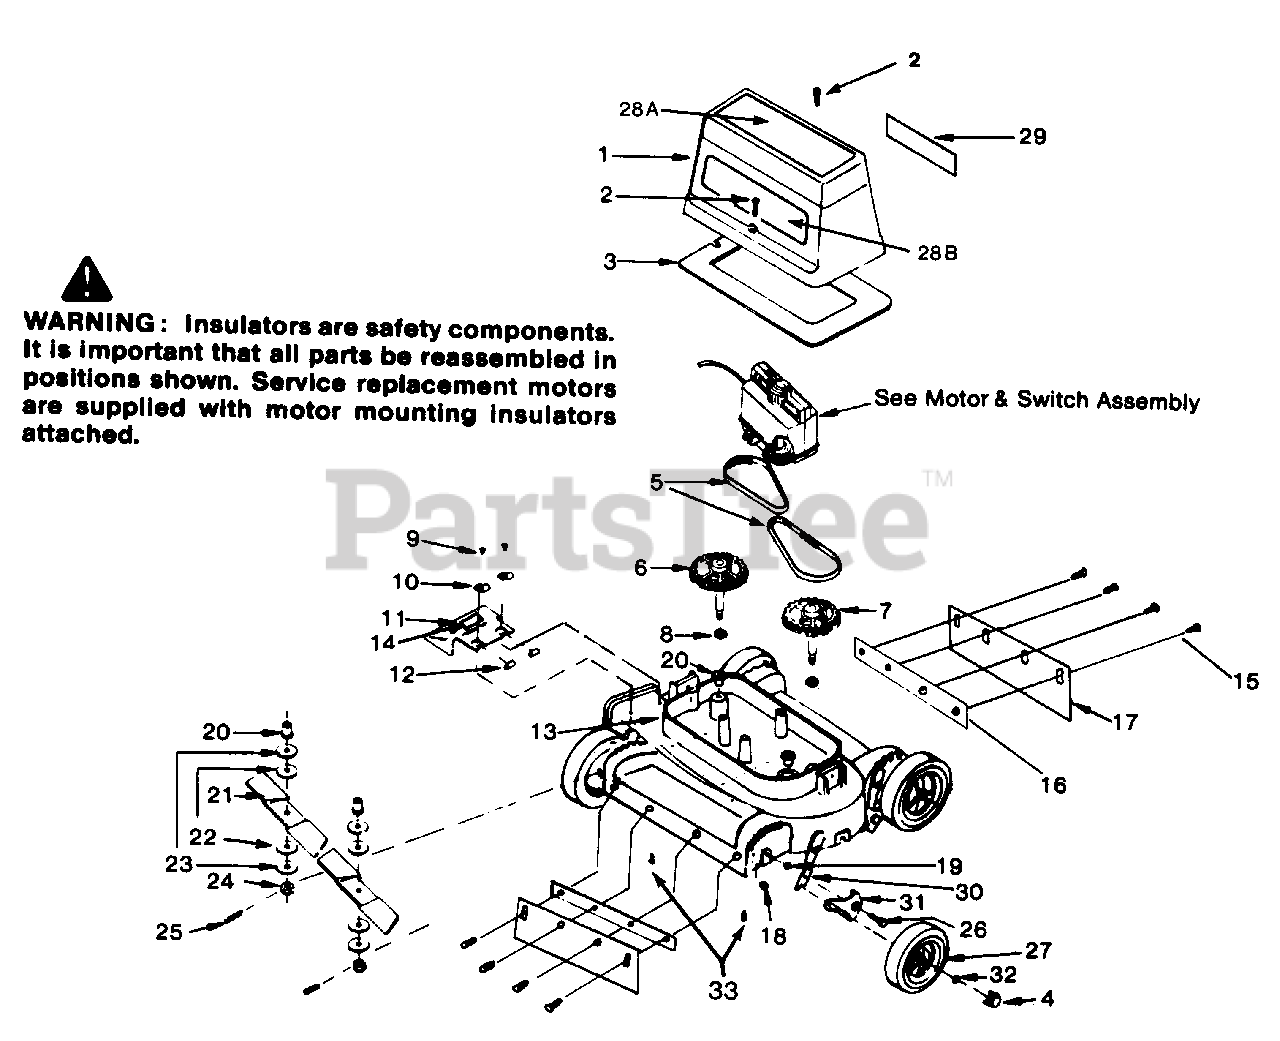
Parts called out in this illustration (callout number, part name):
1	Motor Cover
2	Screw Motor Cover
3	Baffle Air
5	Belt Drive
6	Blade Shaft/Pulley Long
7	Blade Shaft/Pulley Short
8	Washer, Pulley
9	Rivet, Blind
10	Hinge, Chute Guard
11	Chute Guard
12	Hinge Pin
13	Deck Assembly (Incl. Key #20)
14	Label-Danger
15	Rivet-Blind
16	Strap-Trail Shield
17	Trailing Guard
18	Nut
19	Washer, Axle
20	Bearing, Blade Shaft
22	Washer, Fibre
23	Washer, Flat
24	Nut, Blade
25	Cotter Pin
26	Shoulder Bolt
28A	Label-18" Twin Blade
28B	Label-"Simplicity"
29	Caution & Data Label
30	Handle Height Adjustment
31	Bracket & Axle Assembly
32	Retaining Ring
33	Grease Fitting
